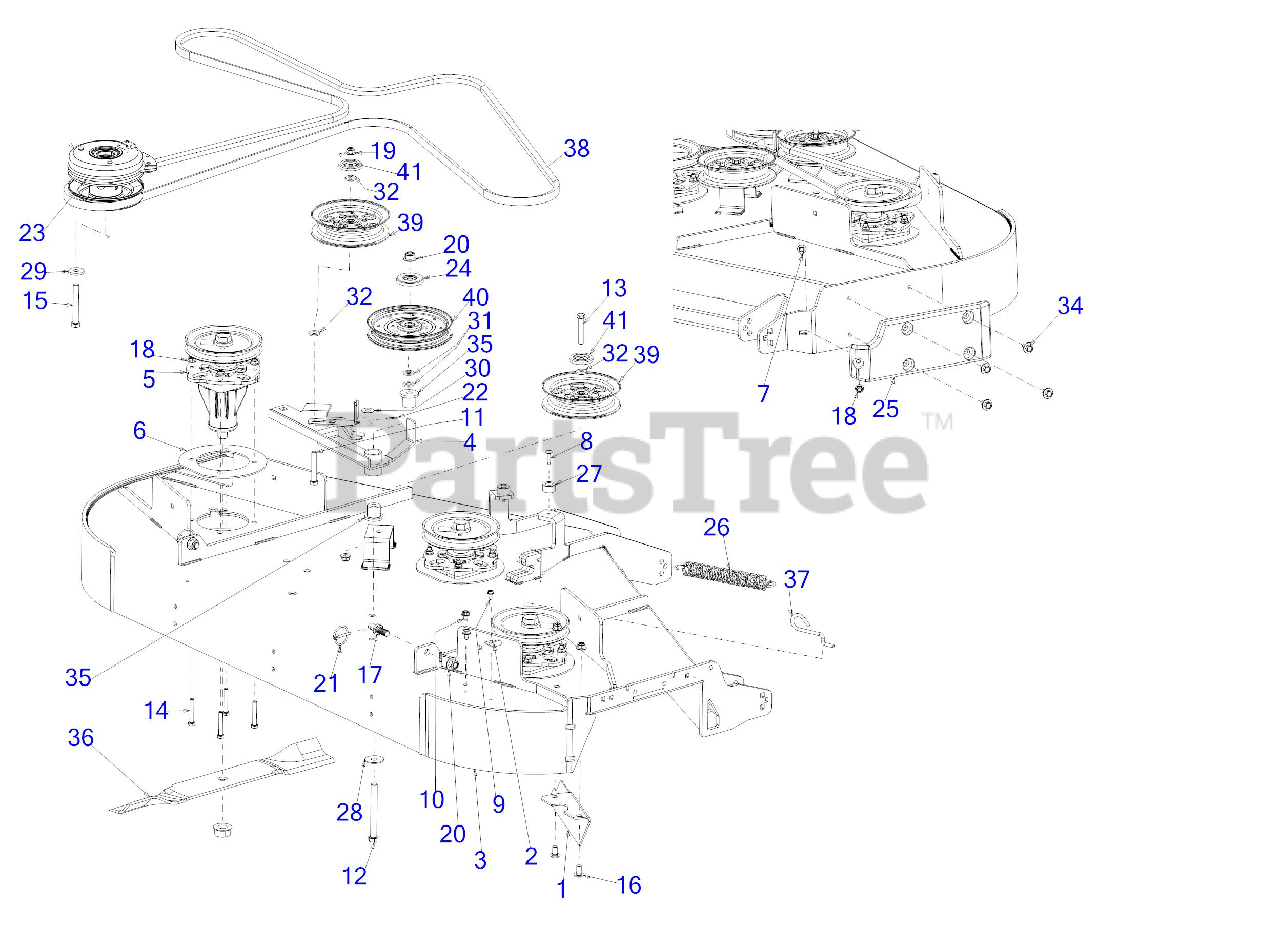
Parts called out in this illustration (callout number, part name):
2	HOOK RETAINER BRACKET
4	DECK IDLER ASSEMBLY
5	SPINDLE ASSEMBLY
7	CARRIAGE BOLT 5/16-18 x 1.00
8	SCREW 1/4-20 x 1.0
9	SCREW 1/4-20 X.500
10	SCREW 5/16-18 x .500
11	HEX SCREW-3/8-16X2.5 GR5
12	SCREW 1/2-13 x 4.5 GR 5
13	SCREW 3/8-16 x 2.25 GR5
14	SCREW 5/16-18 x 2.0 GR5
15	SCREW 7/16-20 x 3.25 GR5
16	CARRIAGE BOLT 3/8-16 x .75
18	FLANGE LOCK NUT 5/16-18
22	COTTER PIN 3/32
23	ELECTRIC PTO CLUTCH
24	PULLEY CAP 1/2"
25	DECK SKID PLATE (LH)
26	EXTENSION SPRING
28	WASHER .51 x 1.5 x .07
29	FLAT WASHER .445 x 1.248 x .170
30	FLAT WASHER
31	FLAT WASHER
32	FLAT WASHER
34	SHOULDER SCREW .43X.29X5/16-18 TT
35	SHOULDER SPACER
36	21" BLADE (HI LIFT)
37	DECK SPRING HOOK
38	DECK BELT B x 161.75
39	IDLER PULLEY 5.0" DIA
40	IDLER PULLEY 6.0" DIA
41	IDLER PULLEY CAP
